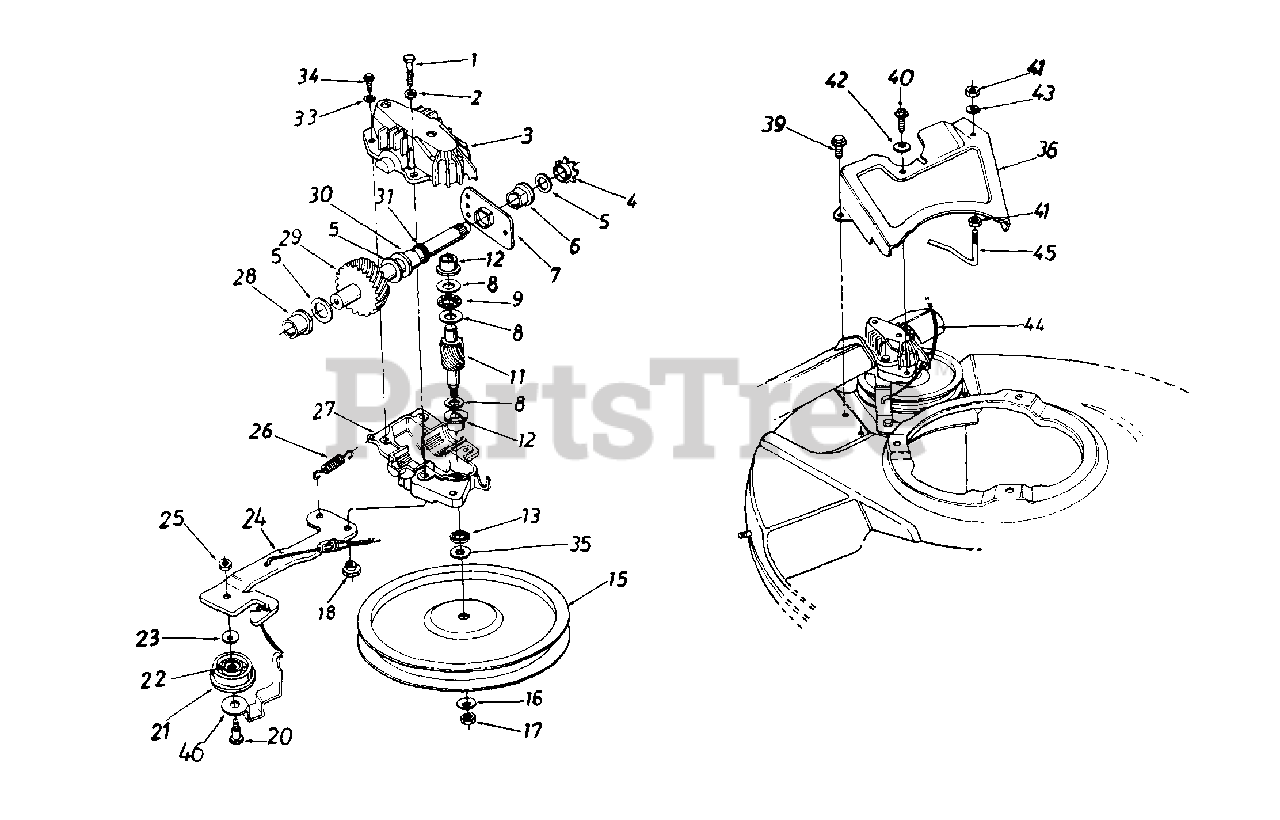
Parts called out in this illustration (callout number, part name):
1	Hex Bolt w/Patch 1/4-20 x 1.25"
2	L-Wash. 1/4" I.D.
3	Upper Hsg. Half
4	#48 Sprocket 7 Tooth x 1/2 Pitch
5	Fl-Wash. 5/8" I.D. x .030
6	Hex Flange Brg. .631" I.D.
8	Thrust Wash. .382" I.D. x .70" O.D.
9	Thrust Bearing .375" I.D. x .812" O.D.
11	11 Tooth Helical Gear
12	Flange Bearing
13	Oil Seal
15	Fl-Pulley 5.06" I.D.
16	Bell-Wash. .265" I.D. x .75"
17	Hex Nut 1/4-28 L.H. Thd.
18	Shld. Spacer .375" Dia. x .170
20	Shld. Bolt .375" Dia. x .40"
21	Fl-Idler Plastic 1.50" Dia.
22	Needle Brg. .375" x .31"
23	Bell-Wash. .265" I.D. x .75"
24	Idler Brk't. Ass'y.
25	Hex Patch L-Nut 1/4-28 Thd.
26	Extension Spring 1.12" Lg.
27	N Lower Hsg. Half
28	Flange Bearing .56 Dia.
29	Shaft Ass'y.
30	Flange Bearing .629 Dia.
31	Oil Seal .625 Dia.
33	L-Wash. #10 I.D.
34	Hex B-Tap Scr. #10 x .62"
35	Hex Washer .26" x .88"
40	Hex B-Tap Scr. 1/4 x .62" Lg.
41	Hex Nut 1/4-20 Thd.
42	Bell-Wash. .265" I.D. x .75"
43	L-Wash. 1/4" I.D.
44	S.P. Cable - 48" Lg.
45	S.P. Belt Guard
46	Belt Keeper
